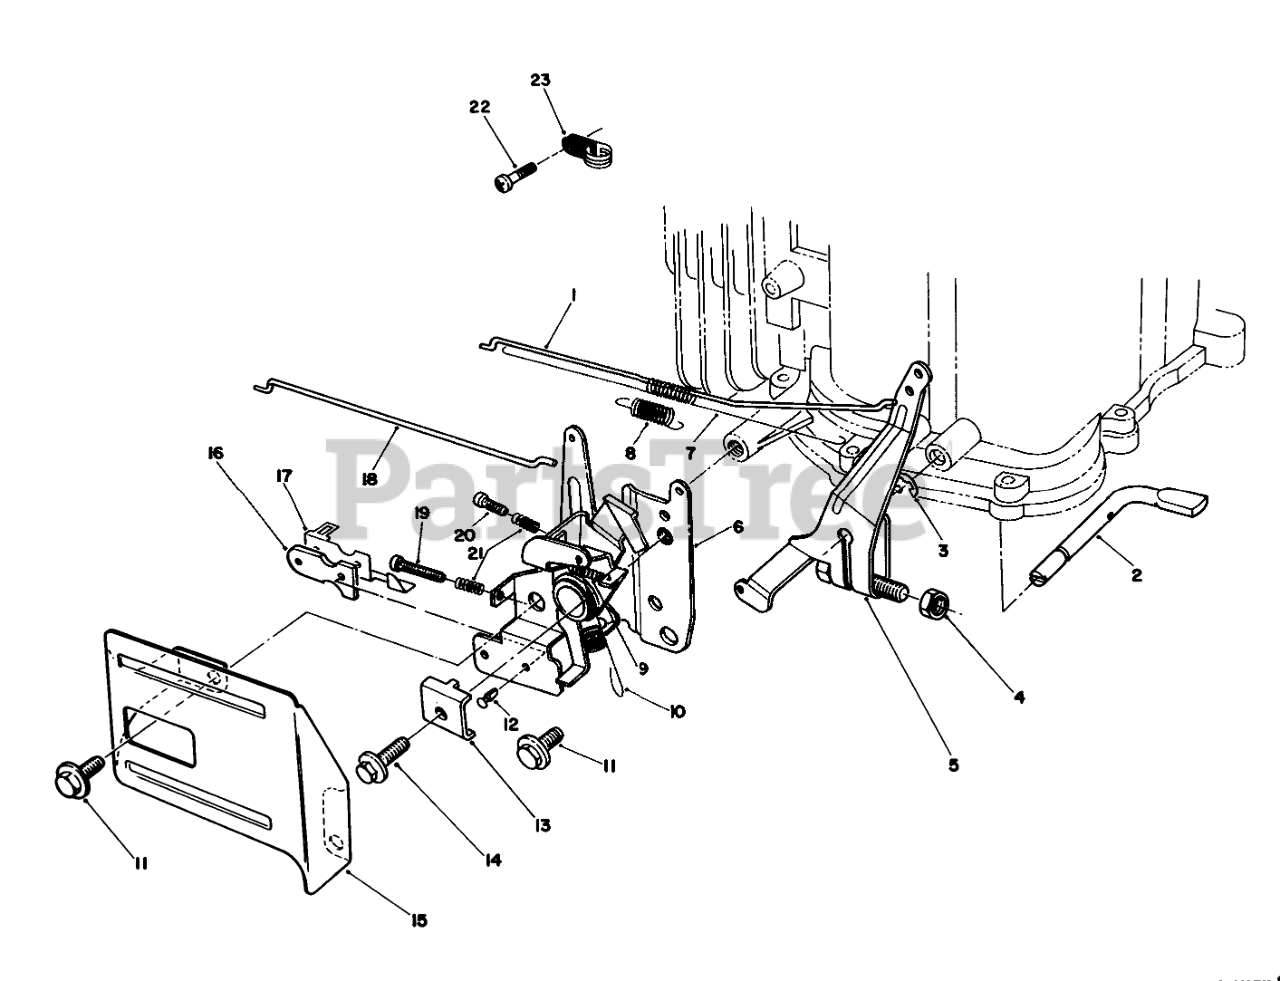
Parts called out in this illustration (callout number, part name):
1	Rod-Carburetor
2	SHAFT
3	E-RING
5	ARM ASM
6	THROTTLE
7	SPRING
8	SPRING
9	SPRING
10	SPRING
12	RIVET
13	CLAMP-CABLE
15	THROTTLE GUARD
16	INSULATOR-KILL SWITCH
17	TERMINAL-KILL SWITCH
18	Rod-Choke
19	SCREW
20	SCREW
21	SPRING
22	SCREW
23	Clamp
